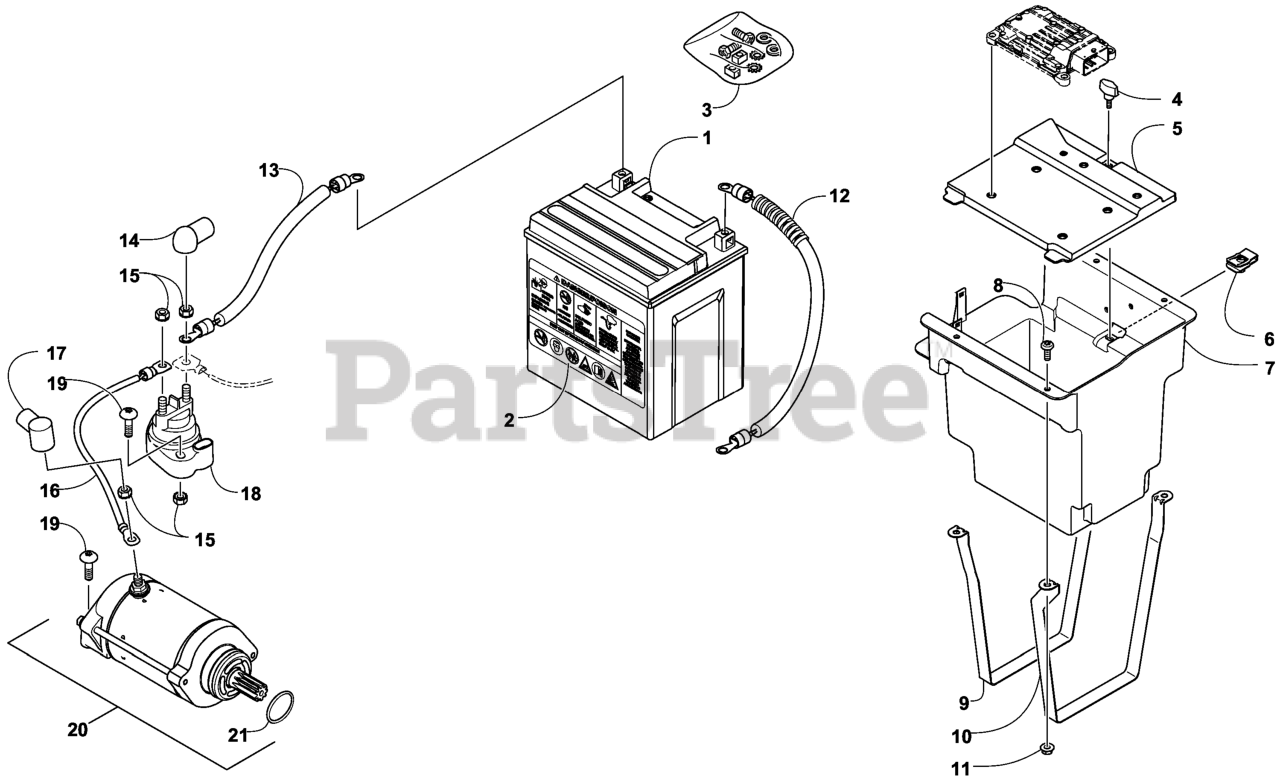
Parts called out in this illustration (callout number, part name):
1	BATTERY-AGM-30AH WET
2	LABEL-POISON/DANGER
3	HARDWARE-BATTERY PACK
4	KNOB-PLASTIC
5	COVER-BATTERY
6	CLIP-U NUT
7	BOX-BATTERY
8	SCREW-TSPRH
9	GUIDE - BELT, 32
10	STRAP-BATTERY BOX, LH
11	NUT-HHF
12	CABLE-BATTERY
13	CABLE-BATTERY, SOLENOID
14	BOOT-TERMINAL, SOLENOID
15	NUT-HH, SEMS
16	CABLE-SOLENOID, STARTER
17	BOOT-TERMINAL, BATTERY
18	SOLENOID-STARTER RELAY
19	SCREW-TSPRH
20	MOTOR-STARTER
